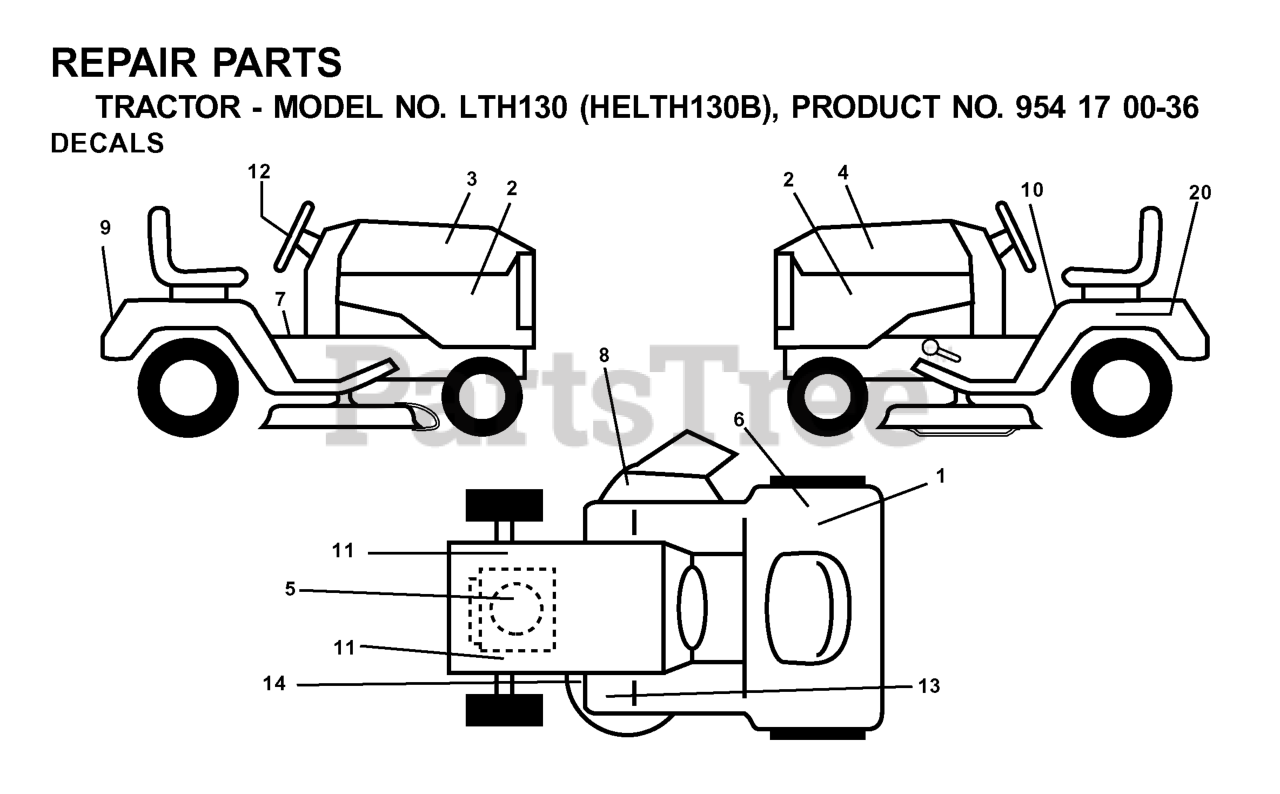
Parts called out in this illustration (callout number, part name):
1	DECAL CERTIFICATION
2	DECAL PNL SIDE
3	DECAL HOOD RH
4	DECAL HOOD LH
5	DECAL HP ENGINE
6	DECAL EUROPE STANDARD CE
7	DECAL PARK BRAKE
8	DECAL MOWER CUT/FINGER
9	DECAL FENDER HUSQ
10	DECAL READ OWNER'S MAN SYMS
12	DECAL.WHEEL.STEERING.HUSQ.PERM
13	DECAL
14	DECAL V-BELT SCHEMATIC
20	DECAL BTRY SYMBOLS
